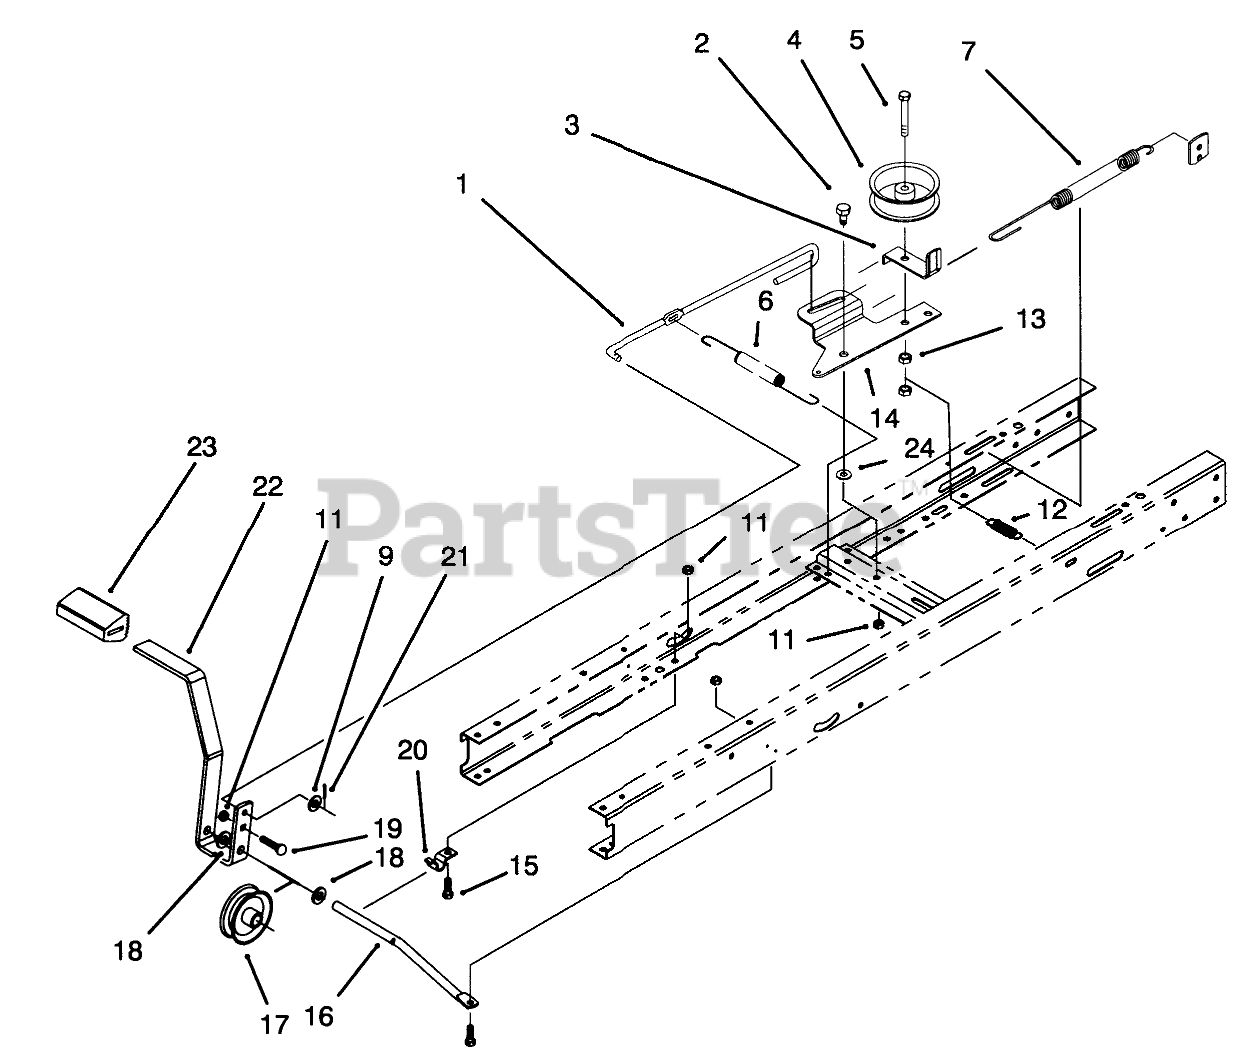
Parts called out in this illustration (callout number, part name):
1	ROD-CLUTCH/BRAKE
2	BOLT-SHOULDER
3	GUIDE-IDLER, BELT
4	Idler Pulley
5	SCREW-HH
6	SPRING-EXTENSION
7	BRAKE SPRING
9	WASHER-PLAIN
11	NUT-LOCK, NI
12	SPRING-EXTENSION
13	NUT-LOCK, NI
14	ARM-IDLER
15	SCREW-HH
16	ROD-PIVOT, PEDAL
17	PULLEY, CABLE
18	WASHER-FLAT
19	SCREW-CARR
20	CLAMP-PIVOT, SHIFT
21	PIN-COTTER
22	Pedal-Clutch/Brake
23	PAD-PEDAL
24	WASHER-PIVOT
